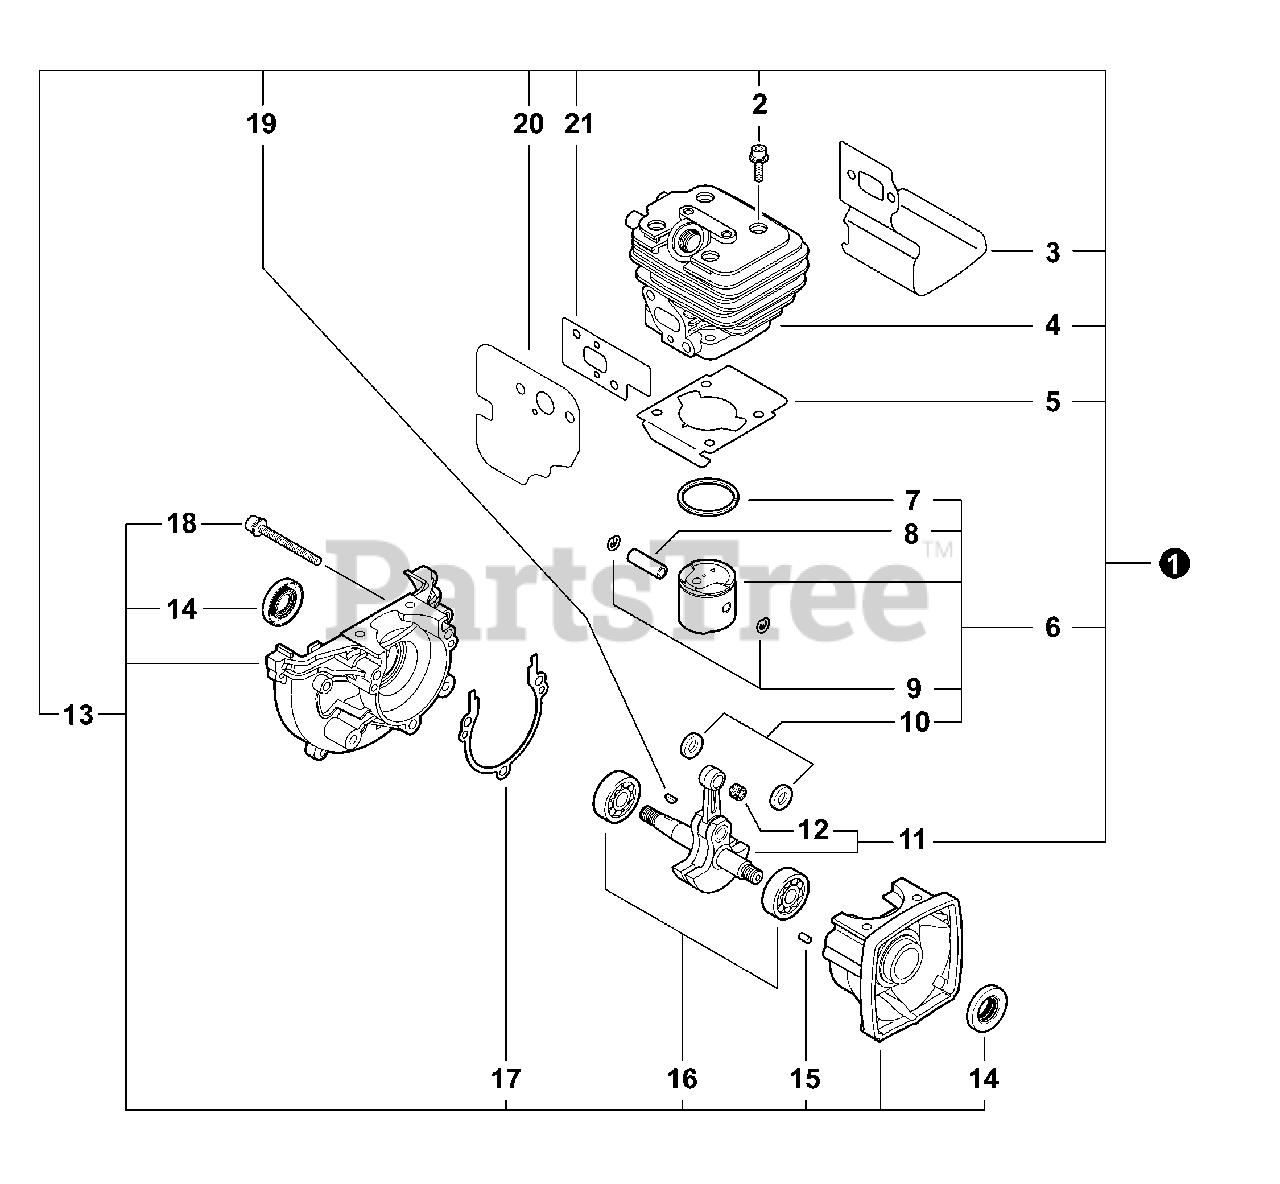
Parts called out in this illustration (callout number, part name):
1	SHORT BLOCK
2	BOLT 5×25
3	HEAT SHIELD, EXHAUST
4	CYLINDER
5	GASKET, CYLINDER
6	PISTON KIT
7	RING, PISTON
8	PIN, PISTON
9	RING, SNAP
10	WASHER, THRUST
11	CRANKSHAFT ASSY
12	BEARING, NEEDLE 8
13	CRANKCASE KIT
14	SEAL, OIL 12
15	PIN, LOCATING 4×8
16	BEARING, BALL - 6201 C3
17	GASKET, CRANKCASE
18	BOLT 5×28
19	KEY, WOODRUFF
20	GASKET, INTAKE
21	GASKET, INTAKE
